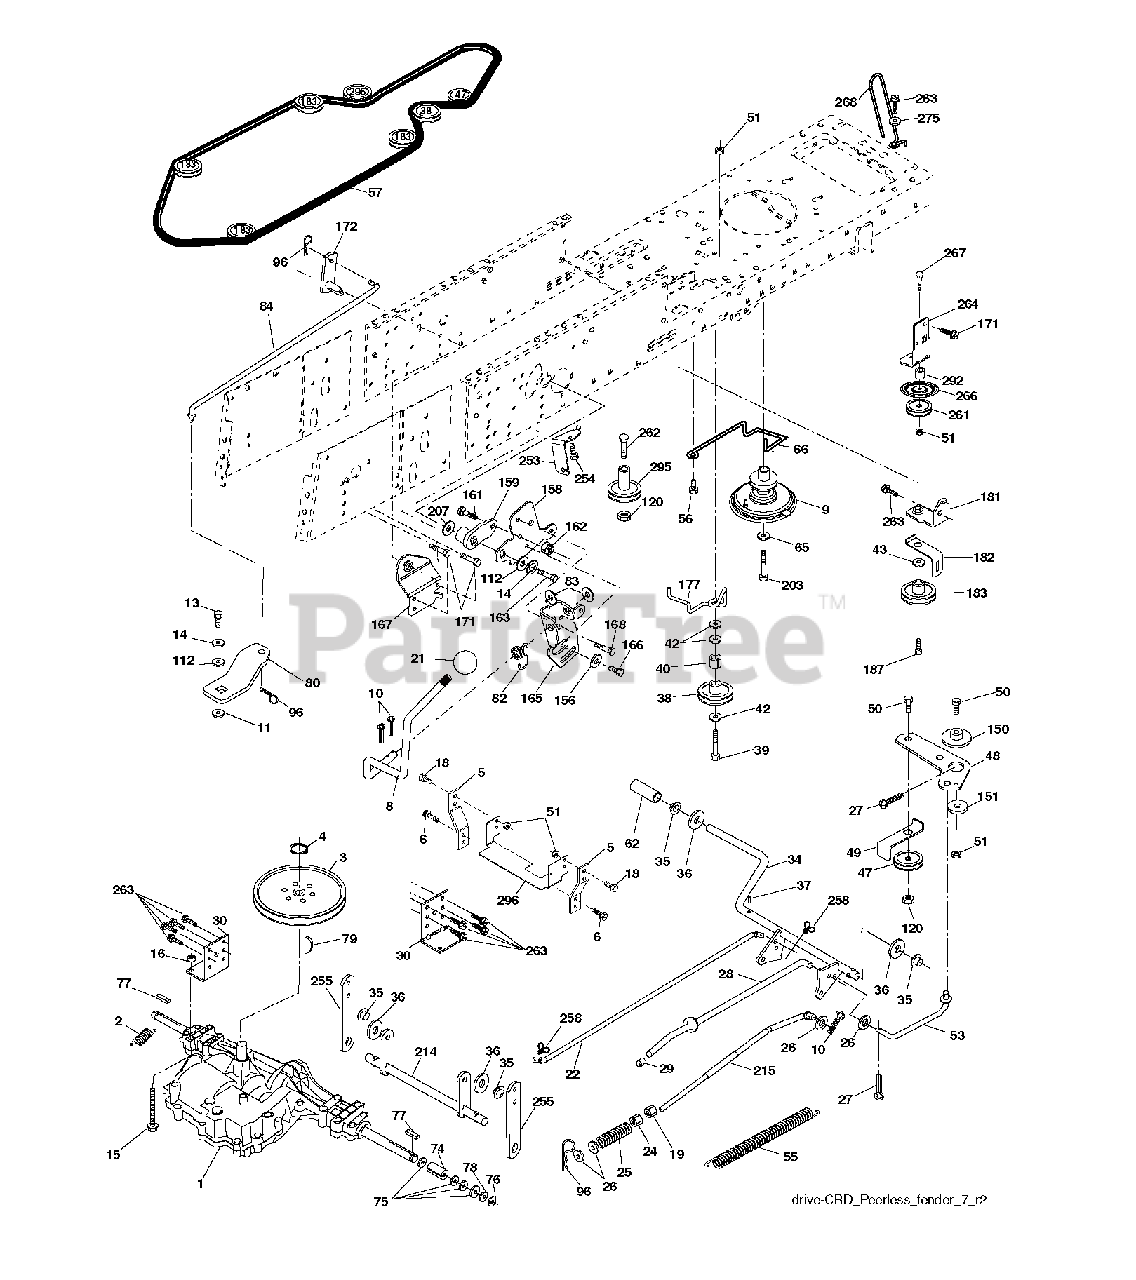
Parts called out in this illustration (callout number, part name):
2	SPRING,BRAKE RETURN
4	RETAINING RING LT
5	STRAP TORQUE
6	SCREW 5/16"
8	ROD SHIFT FENDER ADJUST LT
10	PIN COTTER
11	WASH-SHFT PLT LT
13	BOLT 1/4-28X3/4
14	LOCKWASHER
15	BOLT HEX 5/16-18 GR 5
16	NUT.71038.31-18.HEX.NYLOCK
18	BOLT
19	NUT
21	KNOB.DUCKHEAD.1/2
24	NUT
25	SPRING ROD LT
27	COTTER PIN
28	ROD, PARKING BRAKE
29	PLUNGER CAP
30	BRKT, MOUNT TRNSAXLE
34	SHAFT, FOOT PEDAL
35	BEARING.NYLON
36	WASHER LT
37	DRIVE PIN
38	PULLEY.FLAT
42	WASHER
43	WASHER T
47	IDLER PULLEY
48	BELLCRANK, CLUTCH
49	RETAIN BELT
50	BOLT.3/8-16X1.50
51	LOCKNUT
53	LINK.CLUTCH.7.66.2005
55	SPRING, RETURN LT
56	SCREW.3/8-16
57	V-BELT.KEV.111"
62	PEDAL COVER T
65	LOCKWASHER
66	KEEPER BELT ENGINE
74	SPACER AXLE
76	E-RING LT
77	SQUARE KEY
80	ARM SHIFT
82	SHIFT SPRING
83	WASHER
96	RETAINER M
112	WASHER LT
120	NUT LOCK FLG 3/8-16 UNC
150	BUSHING.BELLCRANK.GRD.DR
151	WASHER 12/32X2X10GA
156	WASHER.SRRTD.5/16
158	BRACKET
159	HUB.SHIFT
161	BOLT
162	NUT.CROWNLOCK.1/4
163	BOLT
165	RP BRACKET
166	SCREW
167	BRACKET
168	BOLT.SHOULDER.5/16-18X
171	SCREW LT
187	BOLT.5/16-18X1.25
207	WASHER NYL
254	SCREW 3/8-16X1
258	CLIP RETAINER
261	FLAT IDLER PULLEY
263	SCREW, 3/8-16X3/4
275	WASHER
279	BOLT
295	PULLEY IDLER COMPOSITE
